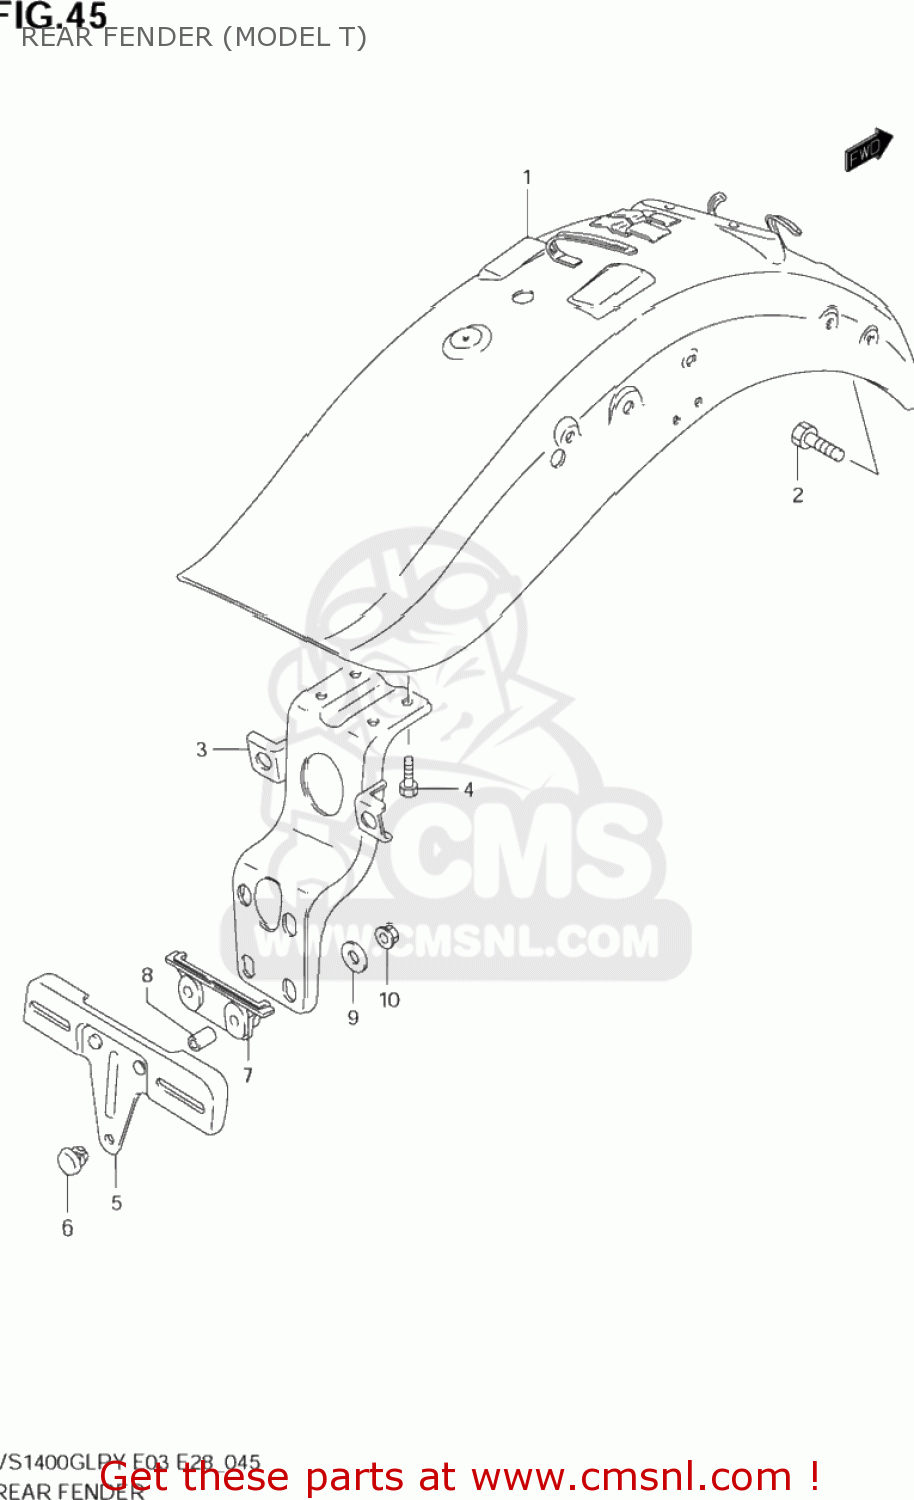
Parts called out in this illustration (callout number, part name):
1	FENDER COMP,REAR
2	BOLT
3	BRACKET,RR COMBINATION LAMP
4	BOLT
5	PLATE,REAR LICENSE
6	CUSHION
7	CUSHION,RR LICENSE PLATE
8	SPACER (5.5X7.5X14.3)
9	WASHER(5.5X20X1.2)
10	NUT
